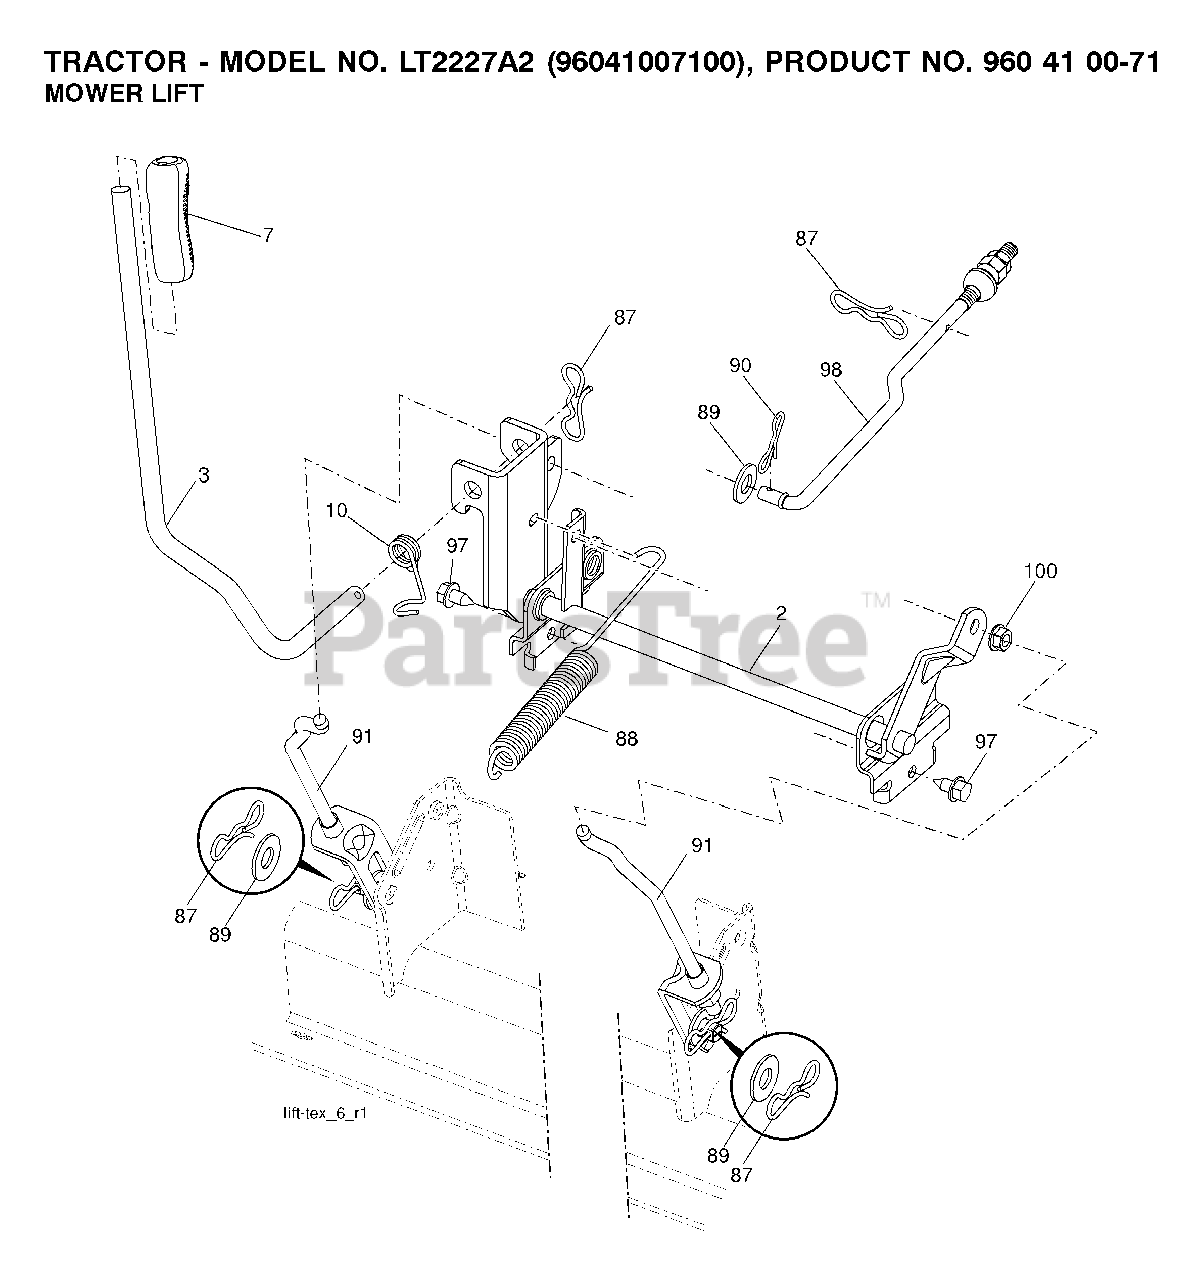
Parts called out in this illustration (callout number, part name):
2	SHAFT.ASM.LIFT.CROSS.H
3	LEVER.LIFT.HANDLE.GT
7	GRIP.HANDLE.LIFT.PVC.BLACK
10	SPRING.TORSION.LIFT.HANDLE
87	PIN.COTTER.7/16.BOW TI
88	SPRING.LIFT.ASSIST.GT2
89	WASHER.CLEAR.ZINC
90	PIN.COTTER.5/16.BOW TI
91	LINK.ASM.LIFT.54"TG
97	SCREW, 3/8-16X3/4
98	LINK.ASM.SUSP.FRONT.MWR.10.5
